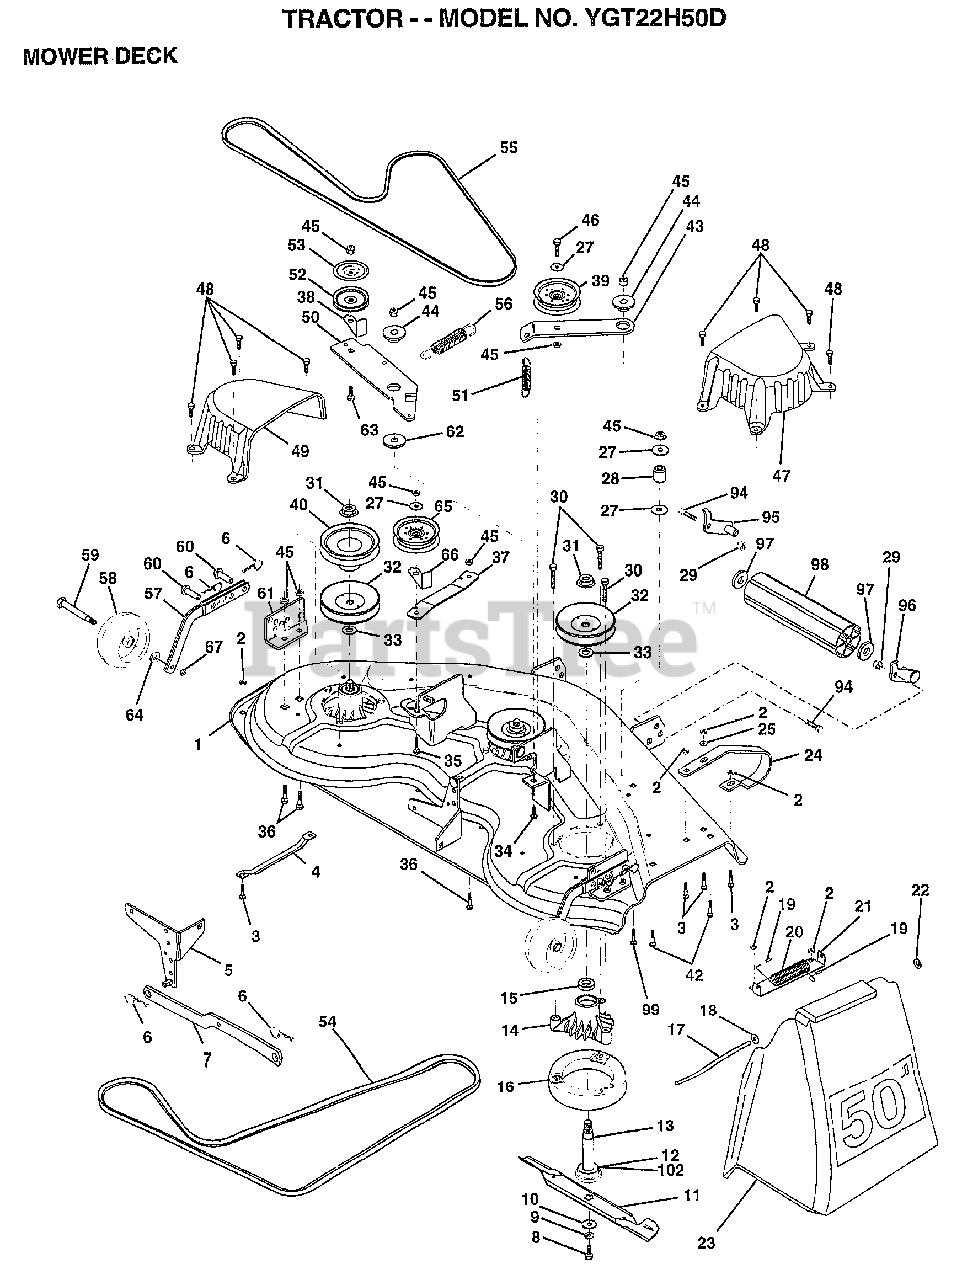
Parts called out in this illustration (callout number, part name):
1	"DECK ASM-50"""
4	RUNNER-LH M
5	BRKT.ASM.SW.44/50
8	BLADE BOLT
10	WASHER.HARD.BLADE
11	"BLADE.50"" HD"
12	BEARING.BALL
13	SHAFT.ASM.W/BRNG
14	HOUSING.MAND.44.V
15	BEARING
16	STRIPPER RND MWR
17	ROD-HINGE T
18	WASHER
19	CAP-SLEEVE LT
20	SPRING TORSION
21	BRKT DEFLECTOR
22	NUT PUSH M
23	DEFLECTOR
24	"RUNNER RH 50"" DK"
25	WASHER M
27	WASHER
29	NUT
30	"SCREW-THD ROLL,WA"
32	PULLEY.MANDREL.42
33	WASHER
34	BOLT.3/8-14X1.25
35	BOLT
36	BOLT D
37	STIFFENER.ARM.IDL
38	"KEEPER-BELT,IDLER"
39	FLAT IDLER PULLEY
40	"PULLEY.DRIVEN.44"""
42	BOLT
43	"ARM.IDLER.SEC.44"""
44	SPACER RETAINER
47	"COVER.MAND.RH.44"""
48	SCREW.1/4-20X5/8
49	COVER.MANDREL.LH
50	ARM.IDLER.PRIMARY
51	"SPRING.SEC.44""VEN"
52	PULLEY.IDLER.VGRO
53	SHIELD.IDLER.44.V
54	BELT V PRIM 50
55	BELT-V.SEC.46.KEL
56	SPRING.EXT.DECK.
57	BAR.ASM.GUAGE.WHL
58	WHEEL GAGE DONUT
59	BOLT.SHOULDER
60	PIN.CLEVIS
61	BRACKET.GUAGE.WHL
62	HARDENED WASHER
63	BOLT.3/8-16X1.50
64	WASHER
65	PULLEY IDELR FLAT
66	"KEEPER-BELT,IDLER"
67	LOCKNUT
94	BOLT
97	WASHER
99	BOLT
102	WASHER.FELT.
